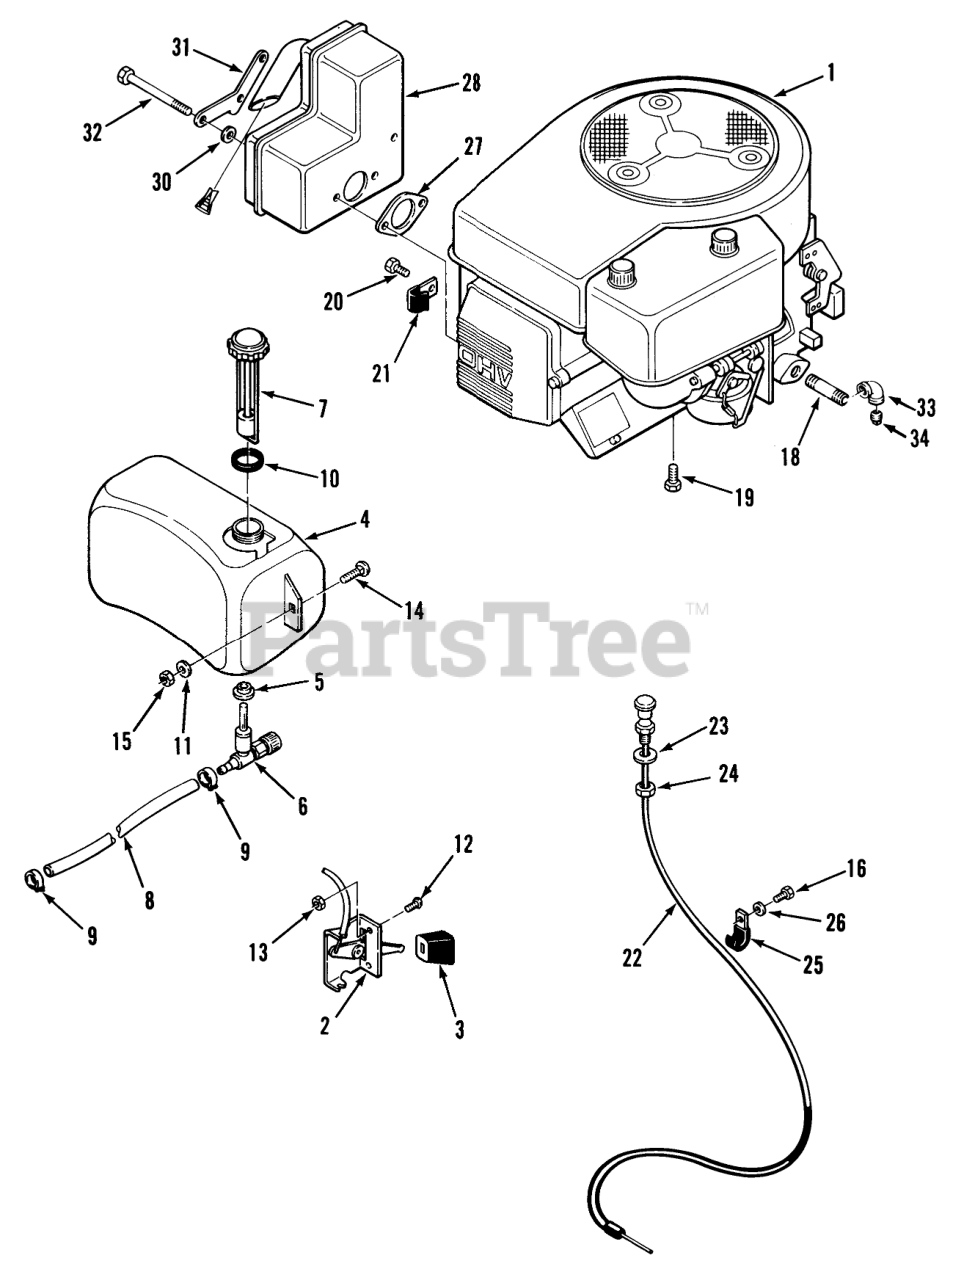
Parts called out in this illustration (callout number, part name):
1	Engine-12HP-Toro Power Plus Model E125V-N/10963B
2	CONTROL THROTTLE
3	KNOB-CONTROL
4	Fuel Tank
5	BUSHING
6	VALVE-FUEL
7	ASSY-FUEL CAP & GAGE
8	Fuel Line 25.5"
9	Clamp
10	GASKET-GAS CAP
11	WASHER 5/16 SAE
12	Screw
13	Nut
14	Bolt
15	Nut
16	Bolt
18	NIPPLE-PIPE (3.5 IN)
19	Bolt
20	HHCS M8X1.25X15
21	J-CLIP
22	CONTROL-CHOKE
23	Washer
24	NUT-HEX PALNUT
25	CLIP
26	Washer
27	Gasket
28	MUFFLER
30	Nut-M8
31	RETAINER-BOLT
32	HHCS-M8 X 100MM
33	Plug
34	ELBOW 3/8 90 DEG
